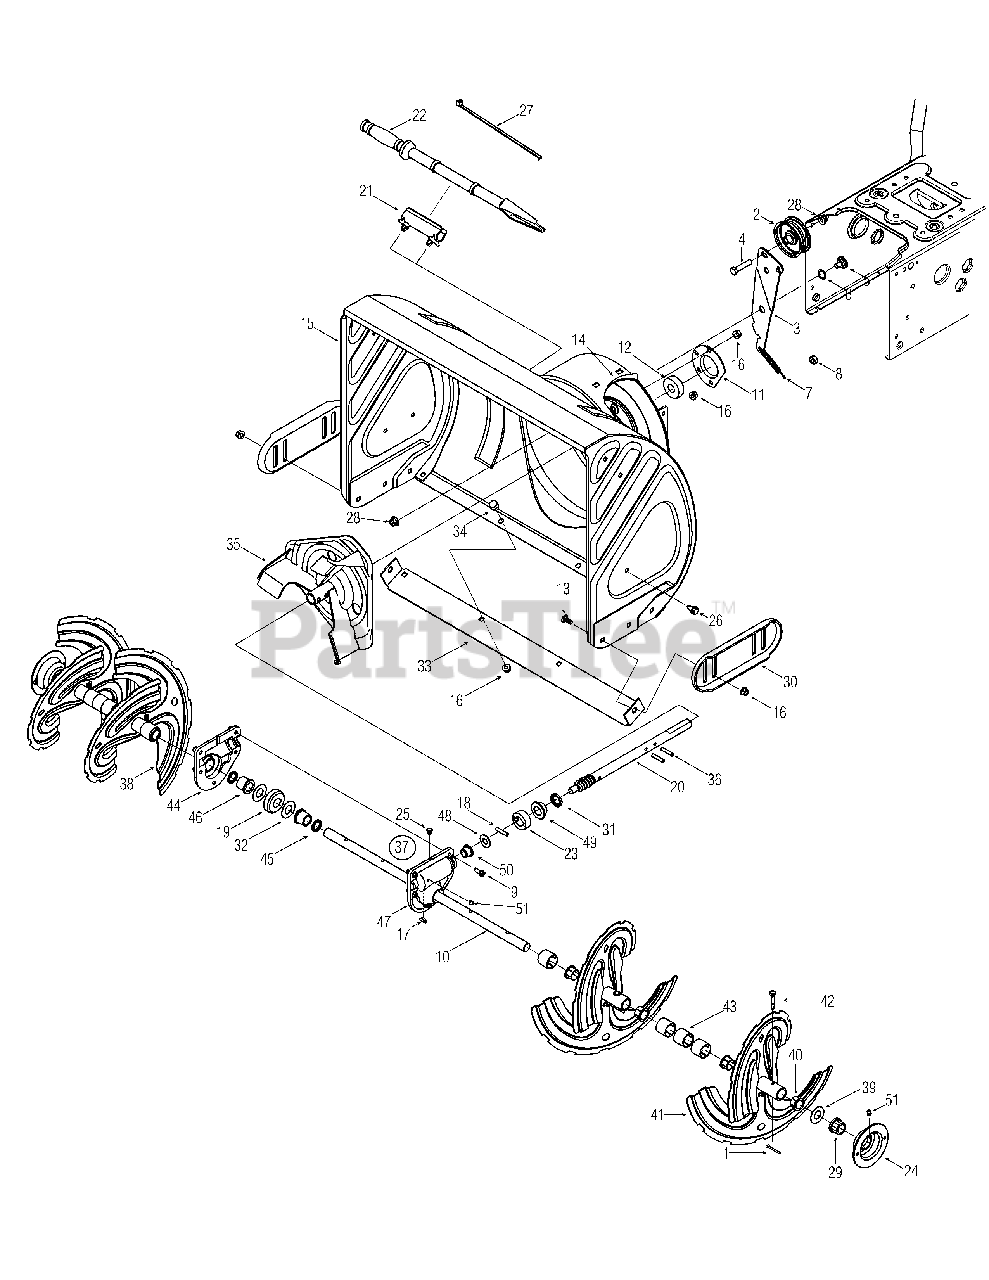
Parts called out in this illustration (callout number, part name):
1	Cotter Pin
2	Flat Idler
4	Hex Cap Screw, 3/8-16 x 1.75
5	Shoulder Screw
6	Wave Washer
7	Extension Spring
8	Hex Nut 5/16-18
9	Self Tapping Screw, 1/4-20 x.75
10	Auger Axle, 28"
12	Ball Bearing
13	Carriage Bolt, 5/16-18 x.75
17	Hi-Pro Key, 3/16 x 5/8
19	Worm Gear, 20-tooth
20	Worm Shaft
21	Clean-Out Tool Mount
22	Clean-Out Tool
23	Thrust Collar
25	Grease Plug
26	Hex Screw, 5/16-12
27	Cable Tie
28	Flange Lock Nut, 3/8-16
29	Hex Flange Bearing
31	Grease Seal
32	Flat Washer,.76 x 1.5 x.030
34	Carriage Bolt 5/16-18 x 1.00
37	Gear Assembly Complete, 28"
39	Flat Washer
40	Flange Bushing
42	Shear Pin,.25 x 1.50
43	Spacer, 1.25OD x.75ID x 1.00 Lg.
44	RH Housing (Incl ref. 45 & 46)
46	Flange Bearing
47	LH Housing (Incl ref. 45 & 46)
48	Flat Washer,.51 x 1.12 x.06
49	Flange Bearing,.75 x 1.0 x.59
50	Flange Bearing,.503 ID x.75 OD
51	Lube Fitting, 3/16 Drive
